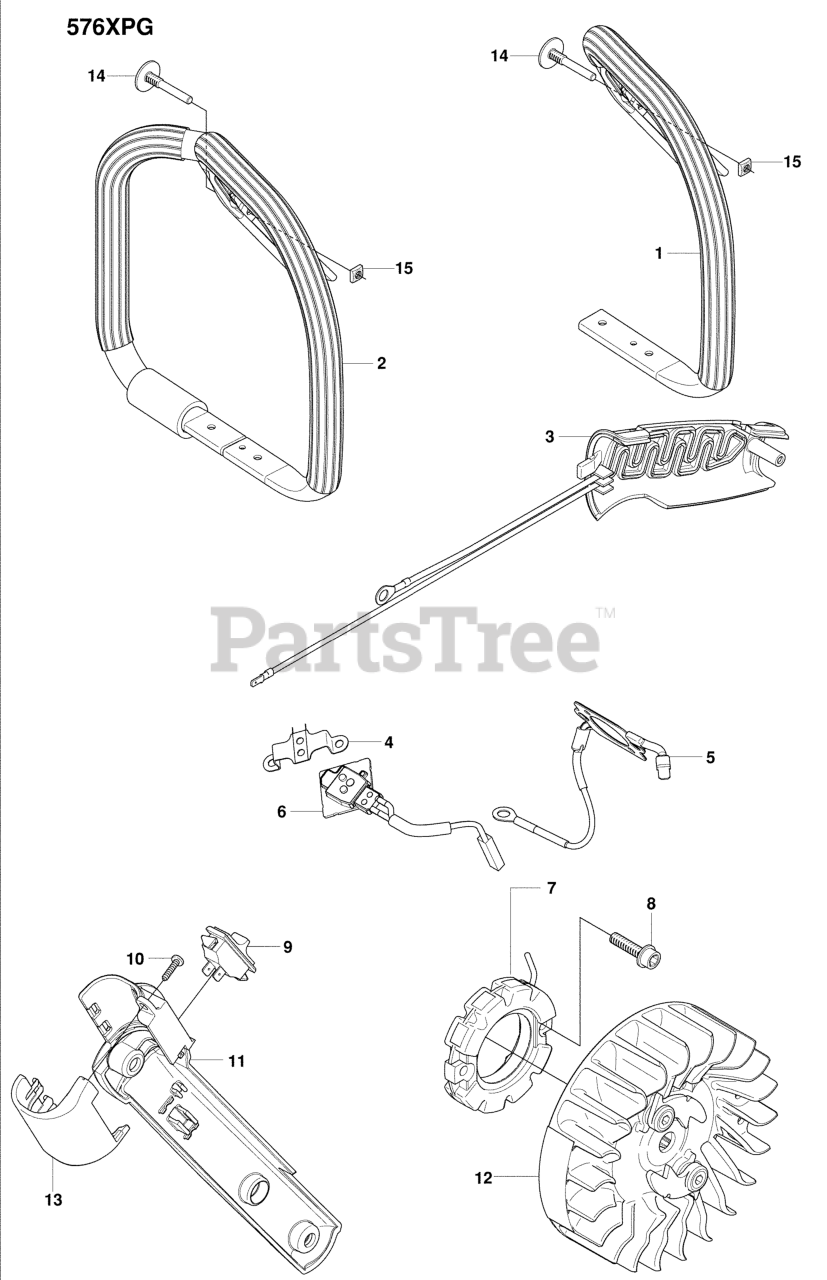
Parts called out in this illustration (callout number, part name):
1	HANDLE (G)
2	HANDLE (WAG)
5	HANDLE CIRCUIT
6	THERMOSTAT
